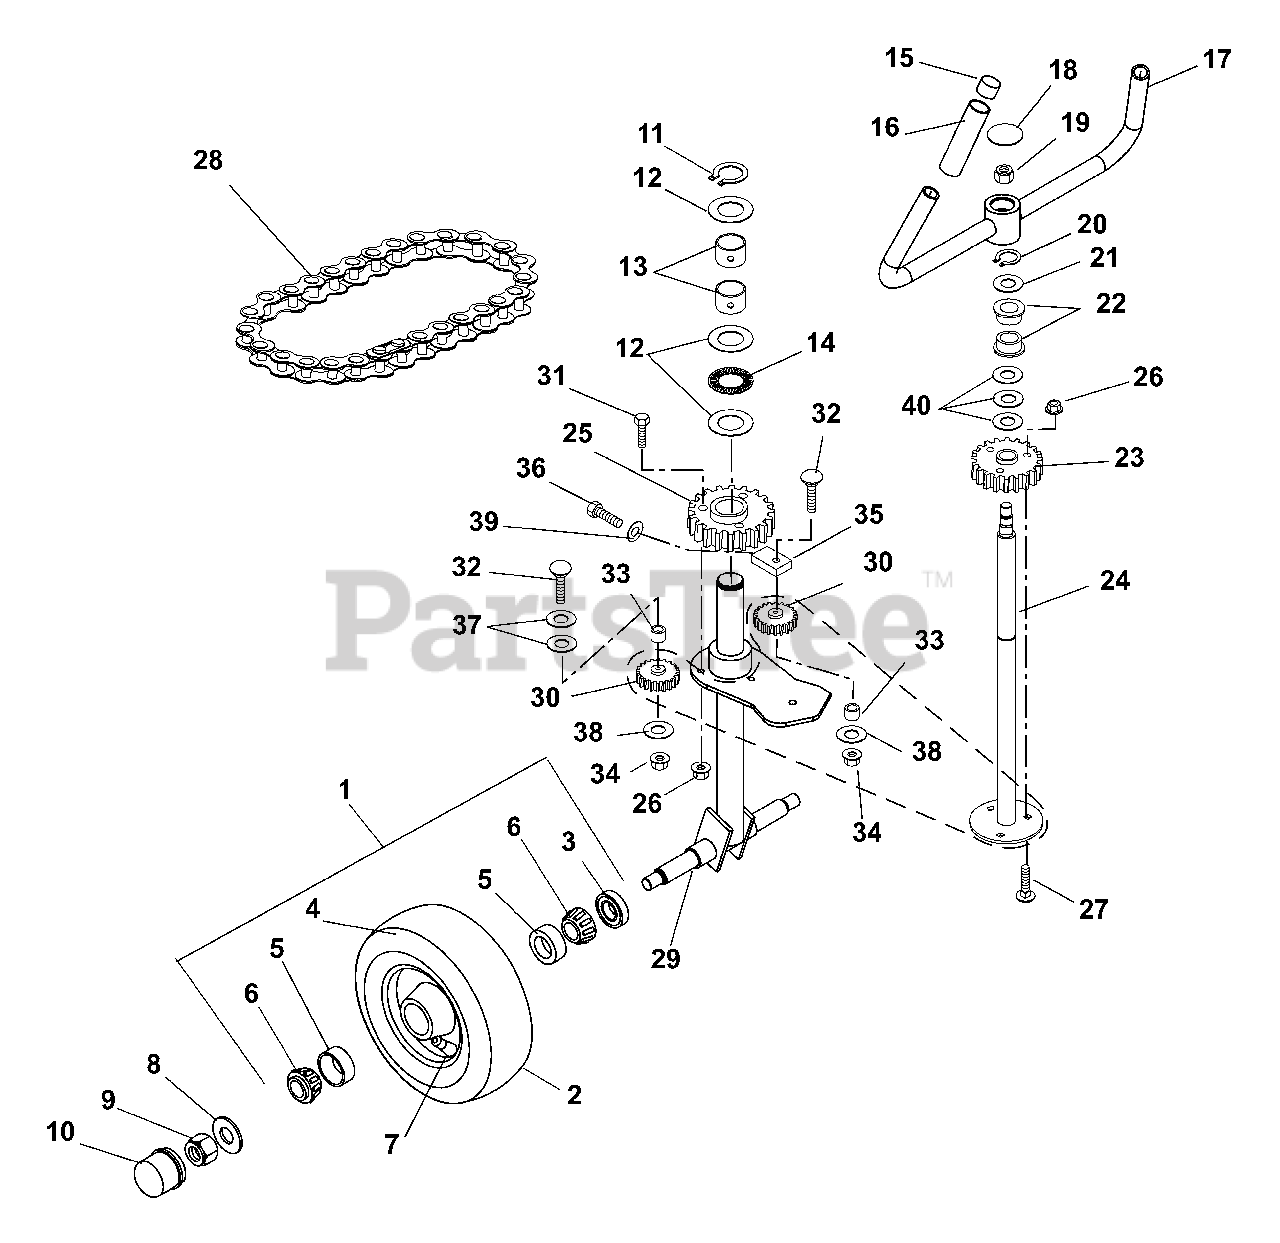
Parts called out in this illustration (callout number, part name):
1	Tire/Wheel Assembly 6.50-8
2	Tire, 16 x 6.5-8 4-Pulley Rib Tread
3	Seal
4	Wheel Assembly 3.75 x 8
5	Bearing-Cup 1.980 x 4.20
6	Bearing, Cone with Grease
7	Valve Stem Assembly
8	Washer, Flat-Steel .812 x 1.50 x .135
9	Nut, Locking-Center .75-10
10	Cap, Dust
11	Ring, Retaining-External 1.50 x 1.38
12	Washer-Thrust 1.502 x 2.18 x .063
13	Bearing-1.00 x 1.13 x 1.00
14	Bearing-Needle-Thrust 1.50 x 2.18 x .078
15	Caplug, Handlebar
17	Weldment, Handlebar
18	Hole Plug 1.38
19	Nut-Locking-Nylon .625-18
20	Ring-Retaining-External .906 x .078
21	Washer-Thrust 1.55 x 1.00 x .09
22	Bushing-Flange 1.02 x 1.38 x .75 x 1.75
23	Sprocket, 23 Tooth #40
24	Weldment, Steering Shaft
25	Sprocket, 28 Tooth #40
26	Nut-Locking-Top-Flange .31-18
27	Bolt-Round Head Square Neck .31-18 x 1.50 Grade 5
28	Chain, #40 x 125 Pitches (62.5")
29	Weldment, Caster Wheel
30	Sprocket, #40 Idler
31	Bolt-Hex .31-18 x 1.75 Grade 5
32	Bolt-Round Head Square Neck .38-16 x 2.25 Grade 5
33	Spacer .406 x .625 x .656
34	Nut-Locking-Top-Flange .38-16
35	Plate, Idler Adjustment
36	Bolt, .31-24 x 1.50 Grade 8
37	Washer-Flat-Steel .406 x 1.125 x .25
38	Washer-Flat-Steel .406 x 1.375 x .135
39	Washer-Flat-Steel .344 x .688 x .065
40	Washer-Flat-Steel 1.12 x 1.500 x .092
